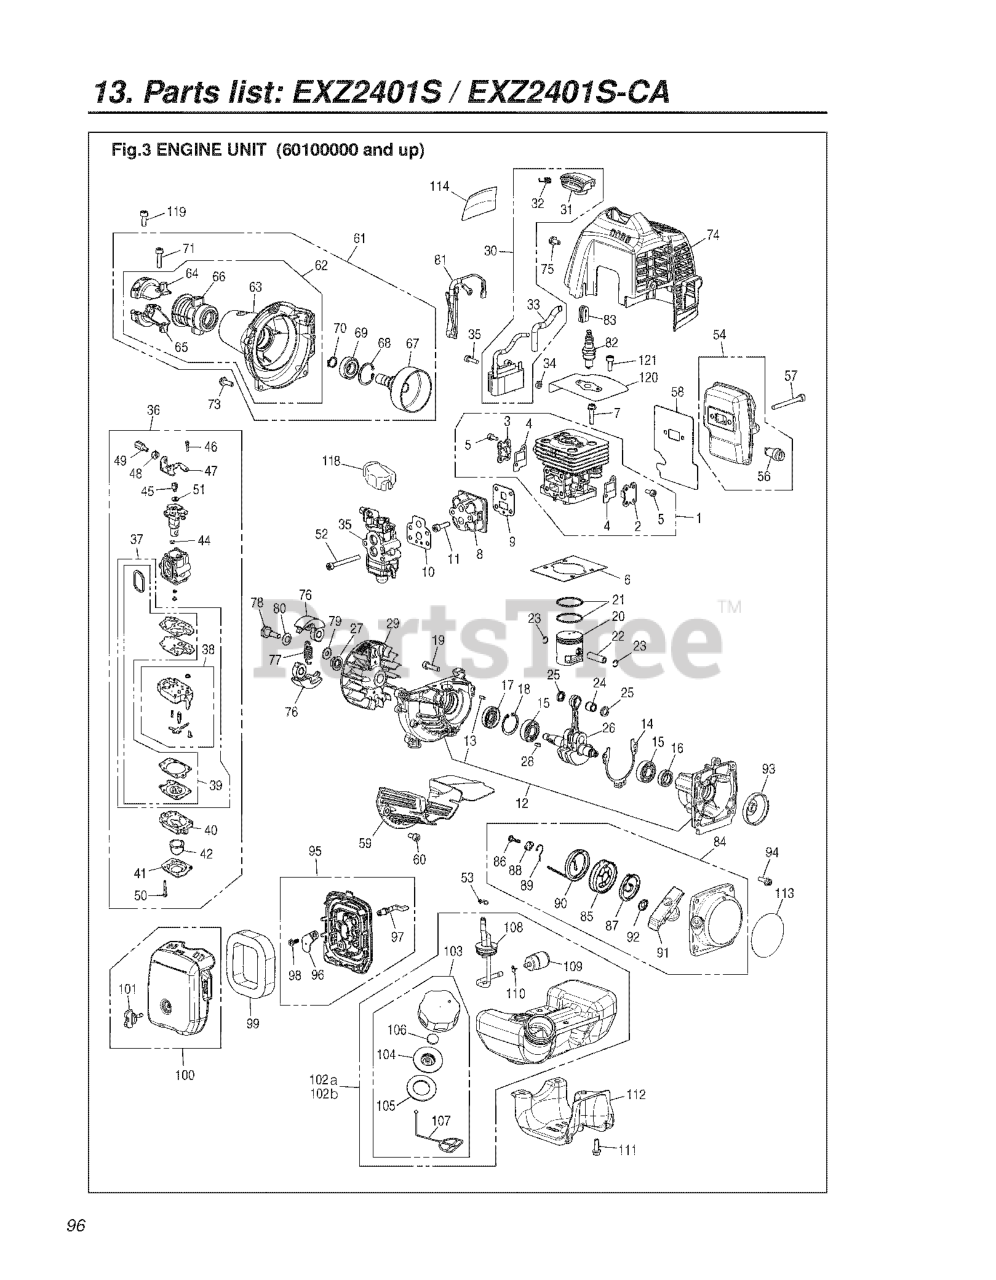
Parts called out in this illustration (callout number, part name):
1	CYLINDER COMPLETE
2	COVER, TR-S
3	COVER, TR-F
4	GASKET, TR
5	BOLT
6	GASKET, BASE
7	BOLT
8	%INSULATOR
9	GASKET.INSU
10	GASKET, CARB
11	BOLT TORX
12	CRANKCASE-C
13	PIN
14	GASKET, CASE
17	SEAL
22	PIN
26	CRANKSHAFT-C
27	NUT
28	KEY
30	COIL-A
31	CAP
34	SPACER
36	CARBURETOR (RPLS 848F088100)
37	REBUILD KIT
38	CARBURETOR BODY
39	GASKET KIT
41	1OVER
44	RING
45	SWIVEL
46	SCREW
47	BRACKET
48	NUT
49	ADJUSTER
51	WASHER
53	CLIP
54	MUFFLER-A***
56	ARRESTER
58	GASKET, MUFFLER
61	HOUSING ASSY (RPLS T155131000)
62	HOUSING
64	BRACKET (A) (RPLS T170031211)
65	BRACKET (B)
67	DRUM (RPLS 481031120-22)
69	BEARING
74	COVER, ENGINE
75	BOLT (RPLS T495051010-11)
81	CORD-COMP
82	(H) SPARK PLUG
84	RECOIL ASSY
87	SPRING, SPIRAL
88	COLLAR
89	SWING ARM
92	PLATE.STOPPER
95	BODY ASSY
96	PLATE.CHOKE
97	LEVER CHOKE
98	SCREW
100	COVER-A (RPLS T155182200)
102A	TANK ASSY (RPLS T155185001)
103	CAP A
104	HOLDER-A
108	PIPE-C
109	FILTER ASSY
110	CLIP
114	LABEL COVER
